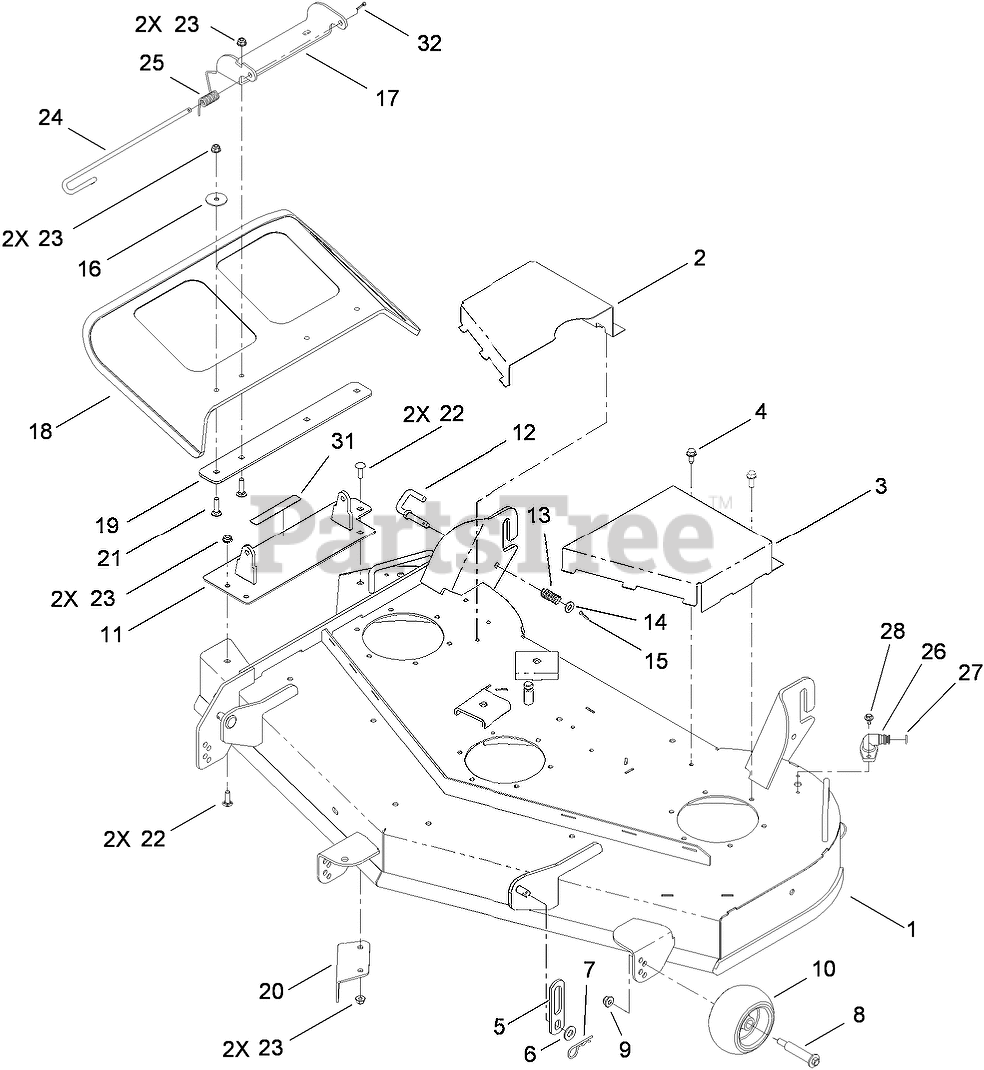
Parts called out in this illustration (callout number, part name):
1	48 INCH DECK AND DECAL ASM
2	COVER-BELT, RH
3	COVER-BELT, LH
4	SCREW-HWHTF
5	LINK-LIFT
6	WASHER-FLAT
7	PIN-COTTER
8	BOLT-SHOULDER
9	NUT-HF, NI
10	ROLLER-SCALP, ANTI
12	PIN-LATCH
13	SPRING-COMPRESSION
14	WASHER-FLAT
15	PIN-COTTER
16	WASHER-FLAT
17	BRACKET-DEFLECTOR, UPPER
18	DEFLECTOR
19	PLATE-DEFLECTOR
20	BAFFLE-CUTOFF
21	SCREW-CARR
22	SCREW-CARR
23	NUT-HF, NI
24	PIN-CHUTE
25	SPRING-TORSION
26	FITTING-WASHOUT
27	O-RING
28	SCREW-HHFTF
31	DECAL-DANGER
32	PIN-COTTER
